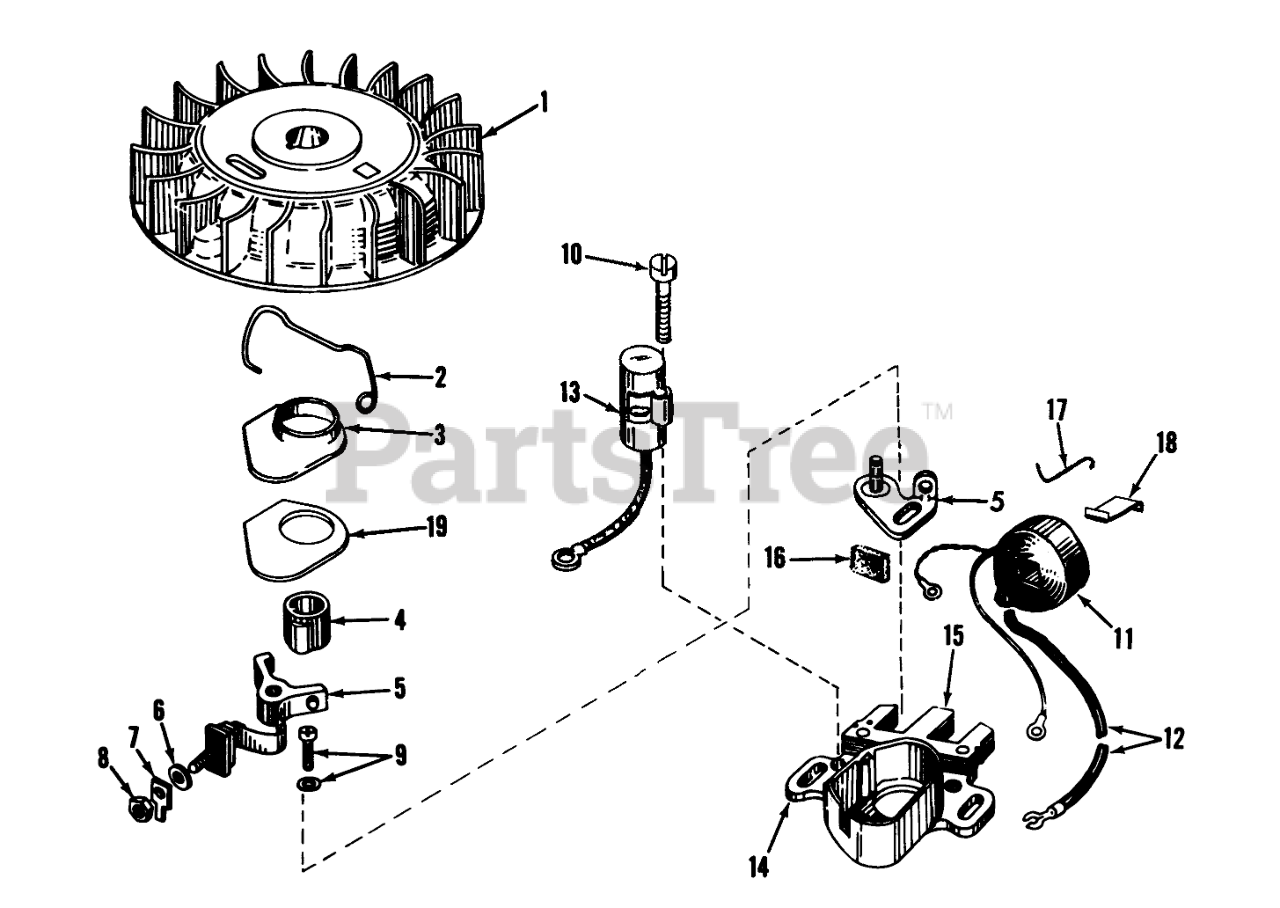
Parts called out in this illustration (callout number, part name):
1	Flywheel
2	Spring Breaker Box
3	Cover, Dust
4	Cam, Breaker
5	Breaker Assy.
7	Terminal
9	Breaker Screw
10	Condenser Screw
11	Coil Assy. (Incl. Ref. No. 12)
12	Wire, Lead
13	Condenser
14	Core & Plate
15	Stator Assy., (Incl. Nos. 2, 3, 5 thru 14 & 16 thru 19)
16	Felt,Cam Wiper
17	Clip, Coil
18	Spring Coil Wedge
19	Gasket Dust Cover
